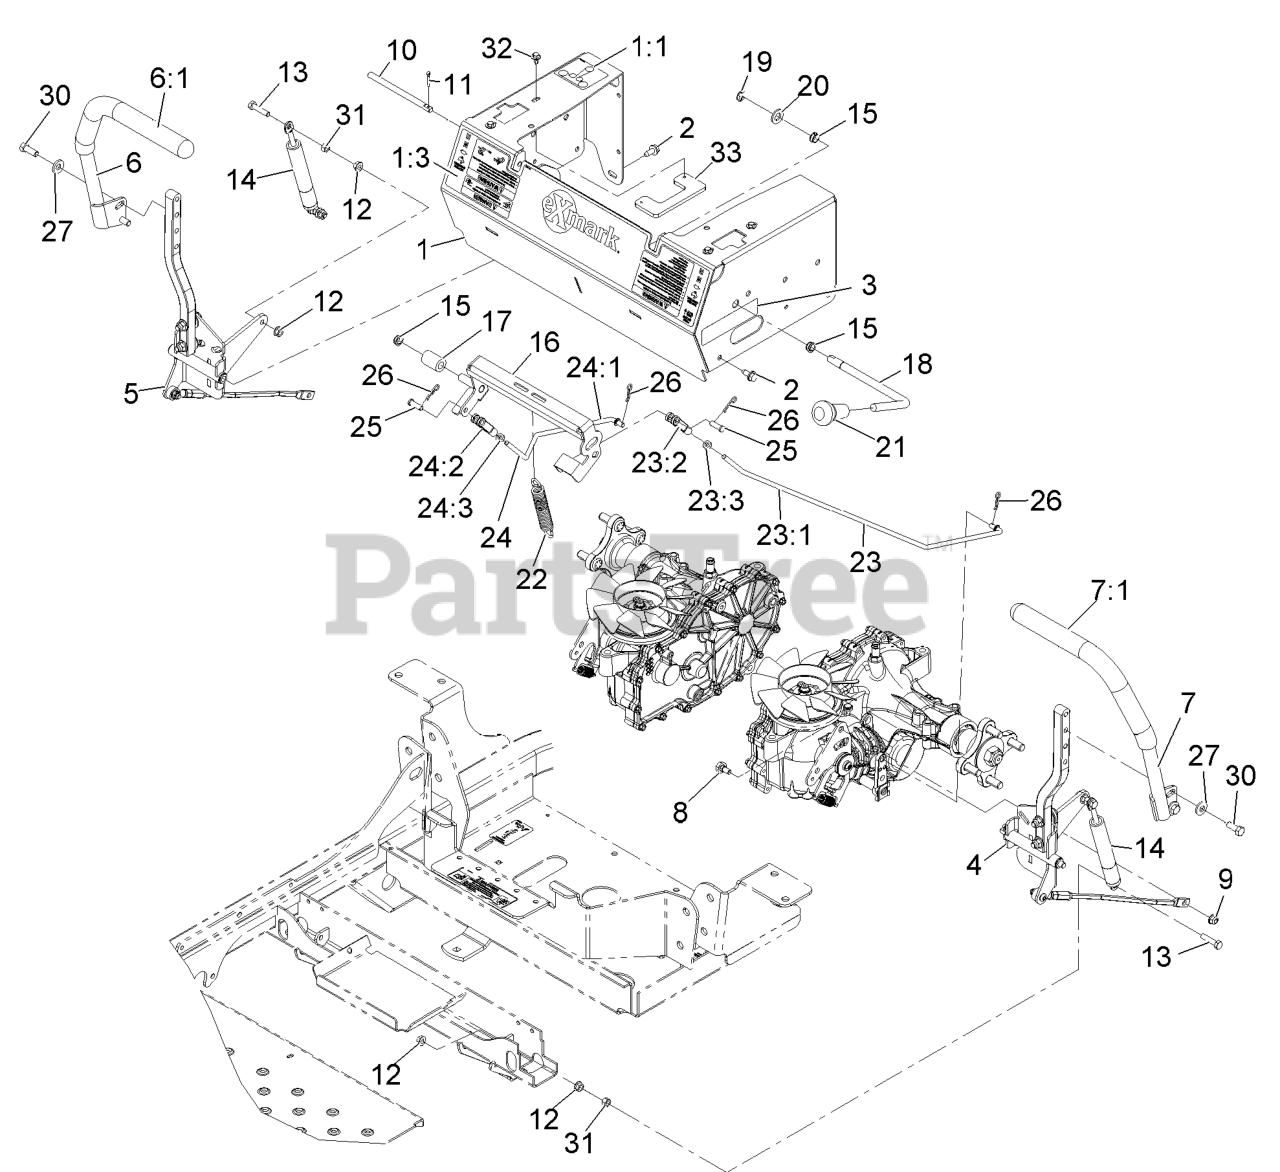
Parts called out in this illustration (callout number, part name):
1	ASM-MOT CTRL FRM W/DCL
1:1	DECAL-ROUTING, BELT
2	Screw-HWH 5/16-18 X 3/4 Tf
3	DECAL-S-SERIES
4	Motion Control Asm-Lh
5	Motion Control Asm-Rh
6	RH HANDLE ASM
7	LH HANDLE ASM
8	BOLT-SHOULDER,HFH
9	NUT-HF, NI
10	PIN-CONTROL PIVOT
11	PIN-COTTER
13	SCREW-HH
14	DAMPER-MOTION CONTROL
15	BUSHING,SNAP
16	ASM-BRAKE CENTER ARM
18	HANDLE,BRAKE
19	RING-RETAINING, EXTERNAL
20	WASHER-FLAT
22	SPRING-DECK, ENGAGEMENT
23	BRAKE LINKAGE ASM-LH
23:1	LINKAGE,BRAKE LH
23:2	YOKE-ADJUSTABLE
23:3	NUT-JAM
24	BRAKE LINKAGE ASM-RH
24:1	LINKAGE-BRAKE, RH
24:2	YOKE-ADJUSTABLE
24:3	NUT-JAM
25	PIN-CLEVIS
26	PIN-COTTER
27	WASHER-BELLEVILLE
30	SCREW-HH
31	NUT-HEX
32	SCREW-HHFTF
33	STOP-MOTION CONTROL
